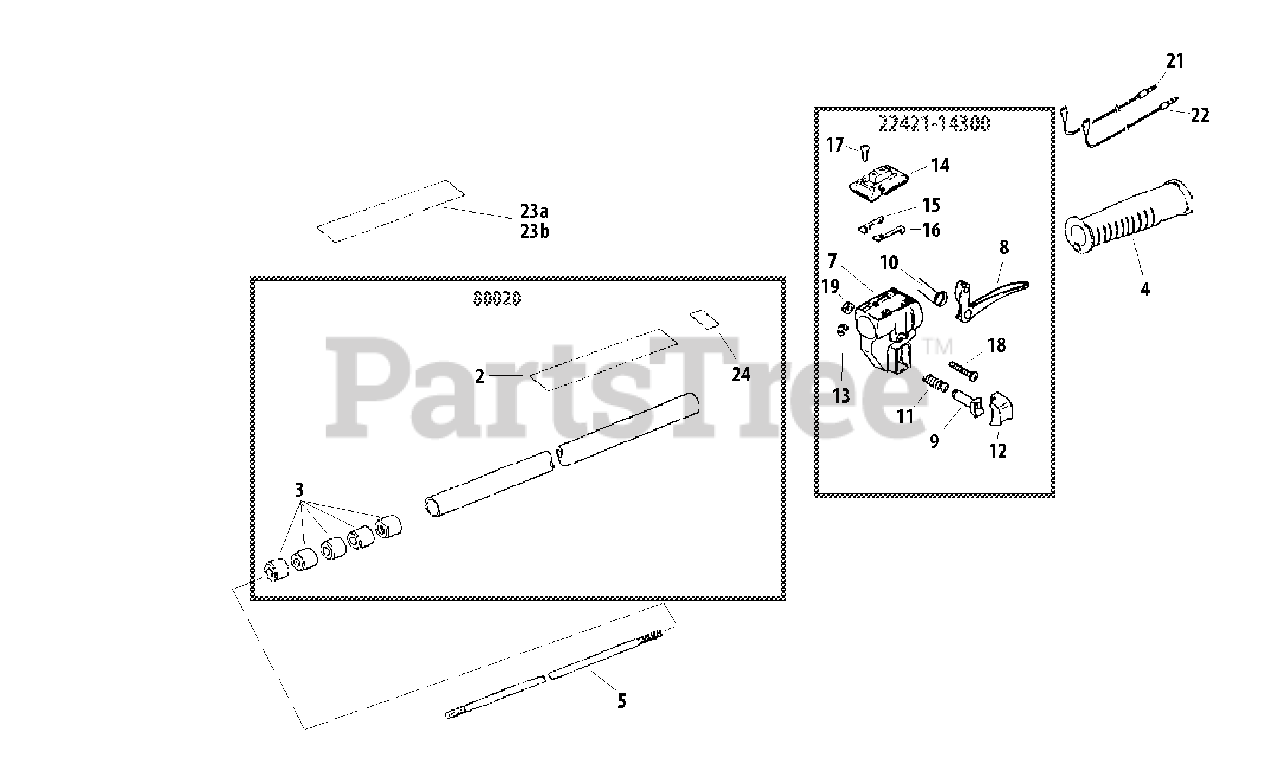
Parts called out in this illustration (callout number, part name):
2	LABEL - CAUTION
3	BUSHING
4	GRIP - REAR
5	PIPE, MAIN
7	BODY, THROTTLE
8	TRIGGER, THROTTLE
9	SHAFT
10	SPRING, TRIGGER
11	SPRING
12	BUTTON, THROTTLE LEVER
13	RING, RETAINING
14	SWITCH, IGNITION
15	TERMINAL - GROUND
16	TERMINAL - GROUND
17	SCREW -- TAPPING
18	SCREW - 5X20
19	NUT - NYLON
21	WIRE - RIGHT
22	WIRE - LEFT
23A	LABEL - MODEL
23B	LABEL - TRADE
24	LABEL - INSTRUCTION
22421-14300	THROTTLE CONTROL KIT
80020	MAIN PIPE ASSY
